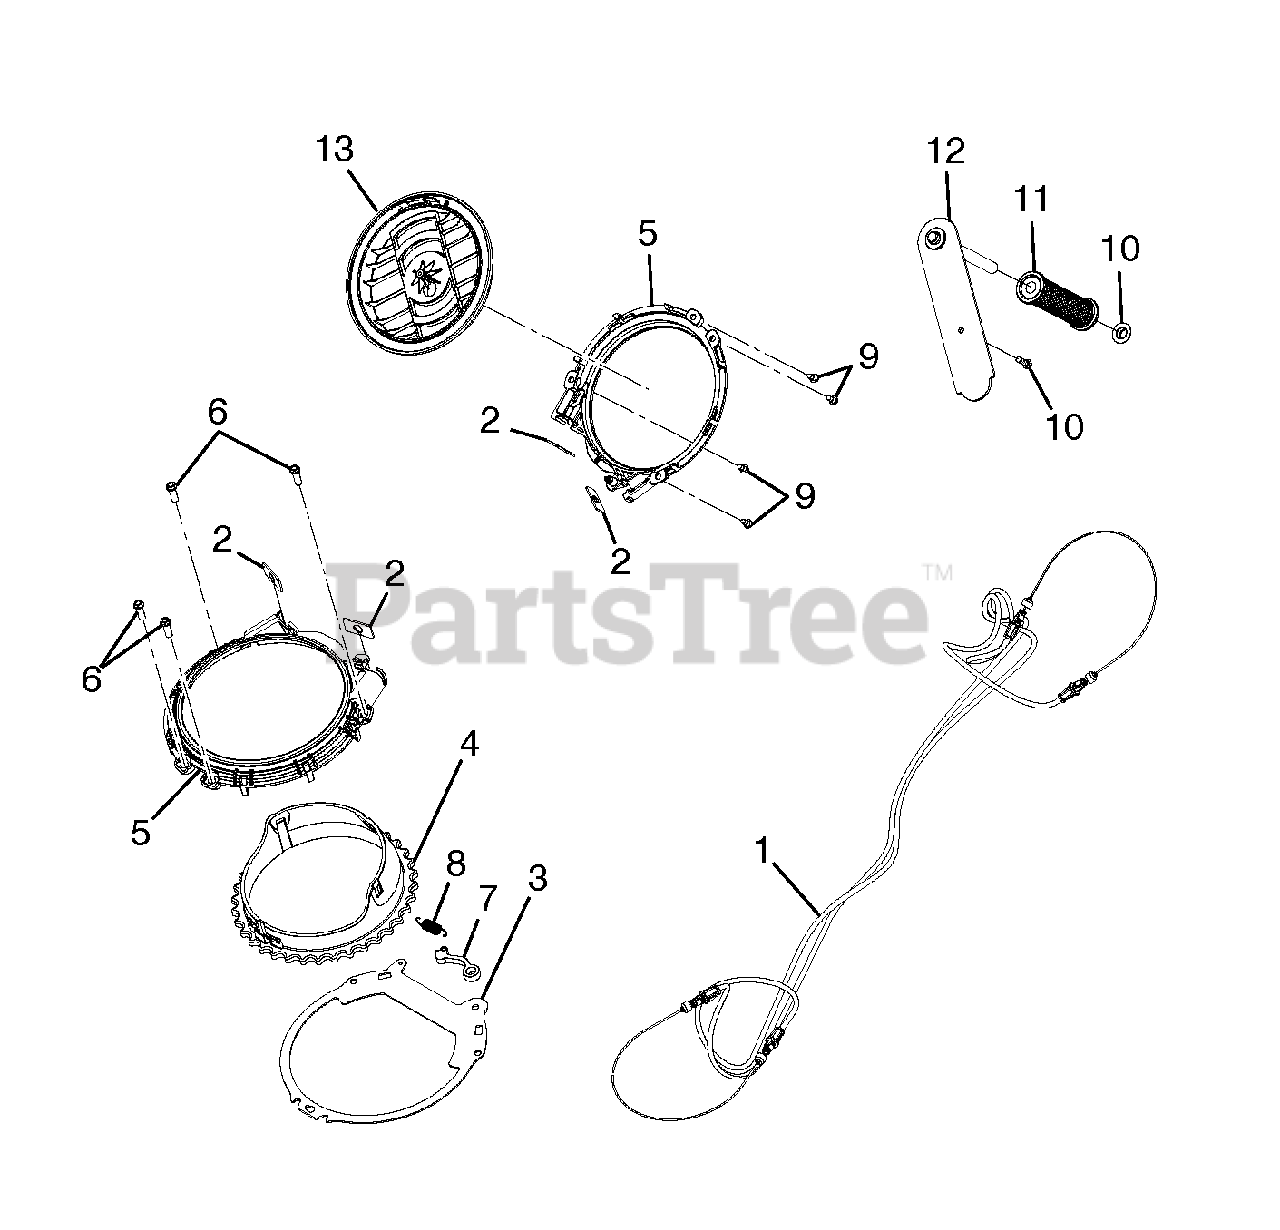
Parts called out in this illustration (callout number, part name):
2	CABLE.BRACKET.DCC
3	PLATE.CHUTE.BASE
4	CHUTE BASE.DCC.BLACK
5	CHUTE RING.RETAINER
6	SCREW.HX.13X.750
7	ARM.CHUTE.RATCHET
9	SCREW.PAN.HD.TORX.1/4-20X.750
10	NUT.PUSH.AXLE.0.5IN
11	GRIP.HANDLE.SUBASM.
12	HANDLE.SUBASM.PIVOT
13	PULLEY.DCC.RING.BLACK
